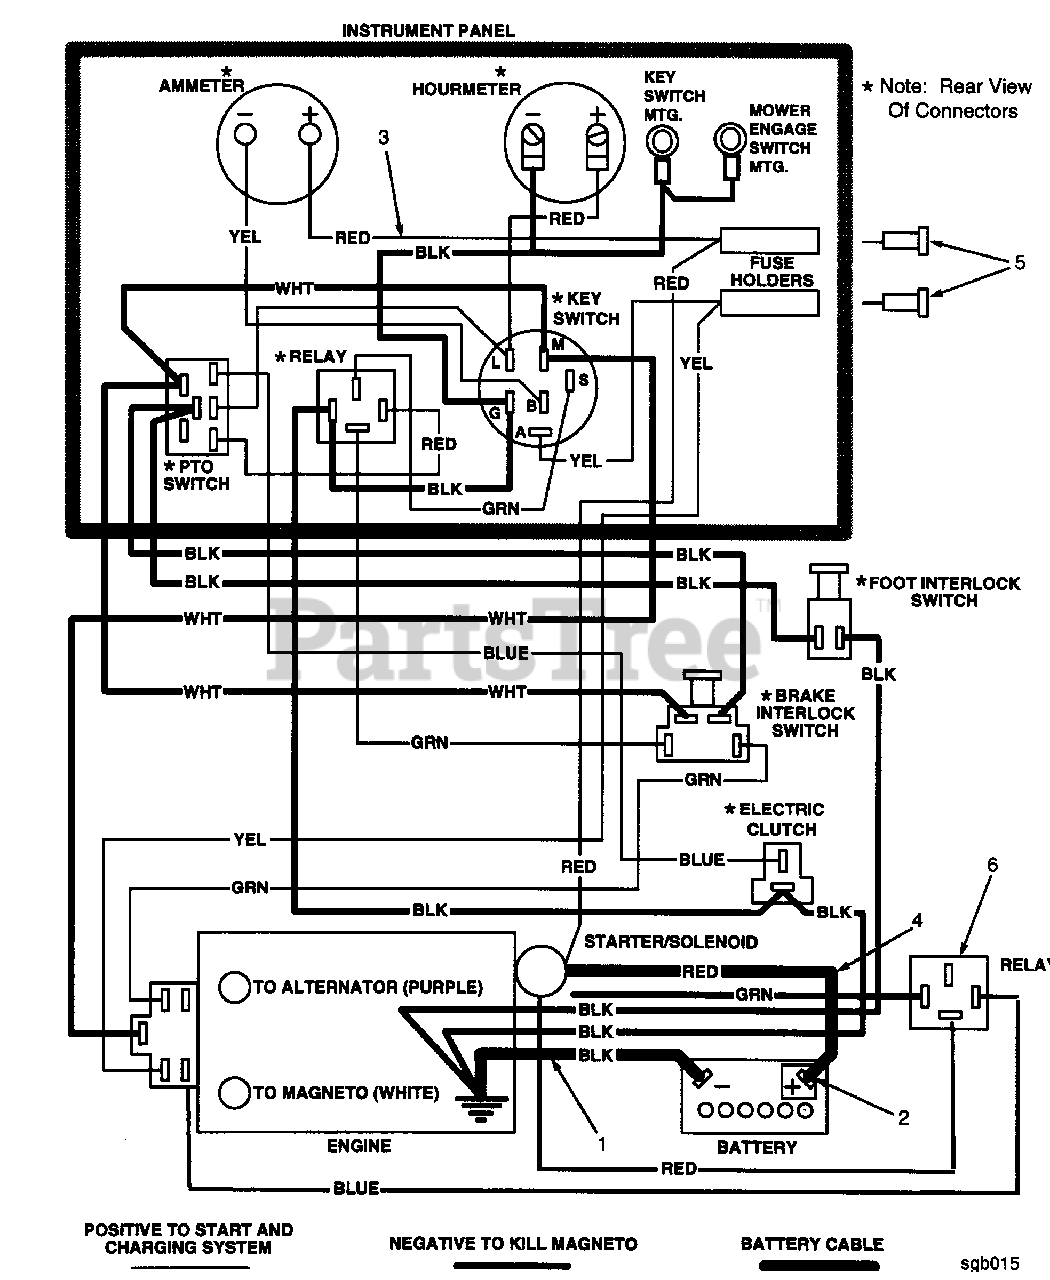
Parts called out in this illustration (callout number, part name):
1	BATTERY CABLE, 36" BLACK
2	RUBBER BOOT
3	WIRE HARNESS, STHM
4	BATTERY CABLE, 25" RED
5	FUSE, 20 AMP BLADE AUTOMOTIVE
6	WIRE HARNESS WITH RELAY
